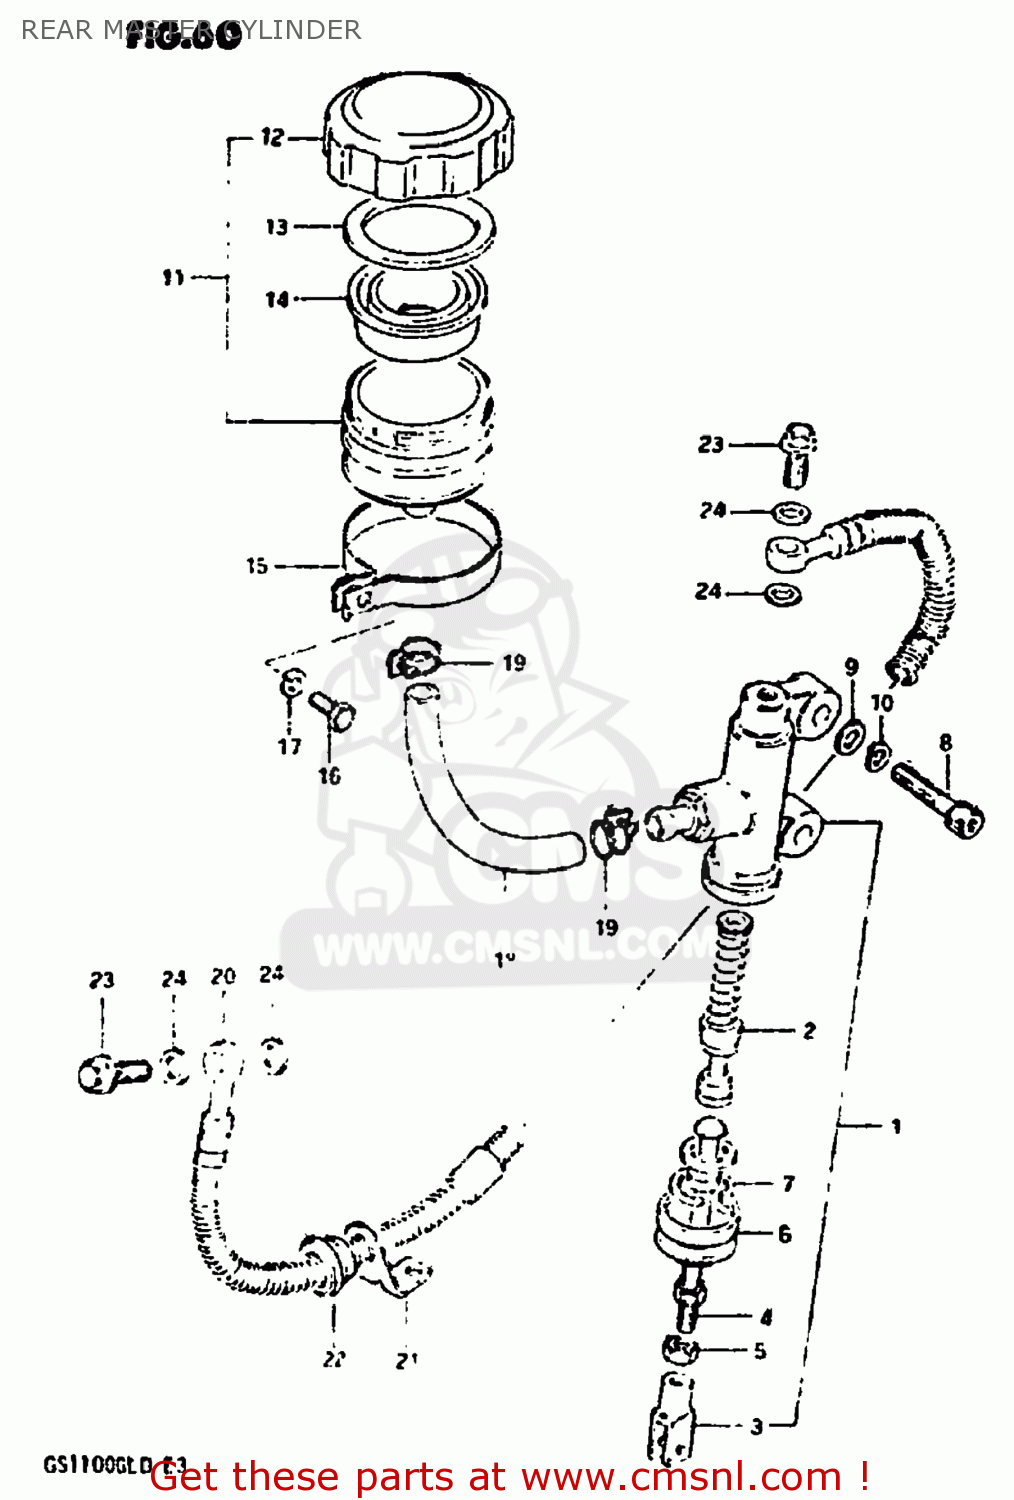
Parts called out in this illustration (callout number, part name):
1	CYLINDER ASSY,RR MASTER
2	PISTON/CUP SET
3	YOKE
4	ROD,REAR MASTER CYLINDER
5	NUT,MASTER CYLINDER
6	BOOT
7	CIRCLIP
8	BOLT
9	WASHER
10	WASHER,LOCK,8.
11	TANK ASSEMBLY,RESERVOIR
12	CAP
13	PLATE,DIAPHRAGM
14	DIAPHRAGM
15	CLAMP
16	BOLT, UPPER
17	LOCK WASHER
18	HOSE,RESERVOIR TANK
19	CLAMP
20	HOSE,REAR BRAKE
21	GUIDE,BRAKE HOSE
22	GROMMET,BRAKE HOSE GUIDE
23	BOLT,UNION
24	WASHER
